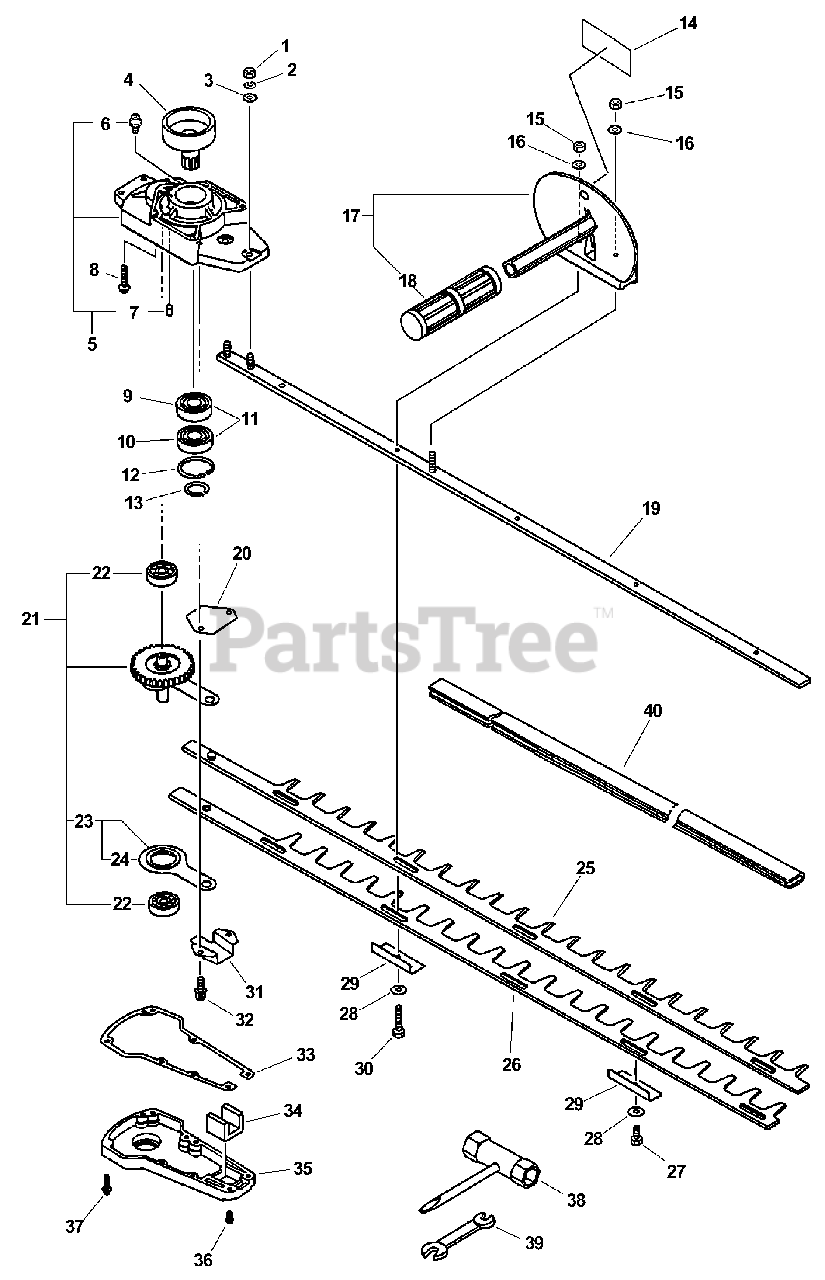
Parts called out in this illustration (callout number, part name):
1	NUT, HEX M6
2	WASHER, SPRING 6
3	WASHER 6.5×11.5×0.8
4	DRUM, CLUTCH
5	CASE, GEAR
6	FITTING, GREASE
7	PIN, LOCATING 4
8	BOLT 5×30
9	BEARING, BALL 6904
10	BEARING, BALL 6904
11	BEARING, BALL 6003
12	RING, RETAINING - 37
12	RING, SNAP 35
13	RING, RETAINING - 19
13	RING, RETAINING - 16
14	LABEL, CAUTION
14	LABEL - CAUTION
16	WASHER 6.5×13×1
17	BRACKET ASSY
19	BAR, FRAME
20	GUIDE
20	PLATE, GUIDE
21	GEAR ASSY
22	BEARING, BALL 6200
23	CONNECTING ROD ASSY
24	BEARING, NEEDLE
25	BLADE - UPPER
25	BLADE, TRIMMER - UPPER
26	BLADE - LOWER
27	BOLT 6×22
29	INSULATOR
30	BOLT 6×40
31	GUIDE
31	GUIDE, BLADE
32	BOLT 5×14
33	GASKET, GEAR CASE
35	LID, GEAR CASE
36	SCREW 4×14
37	SCREW 4×22
38	T-WRENCH 13×19×180
39	SPANNER 8×10
40	SCABBARD
